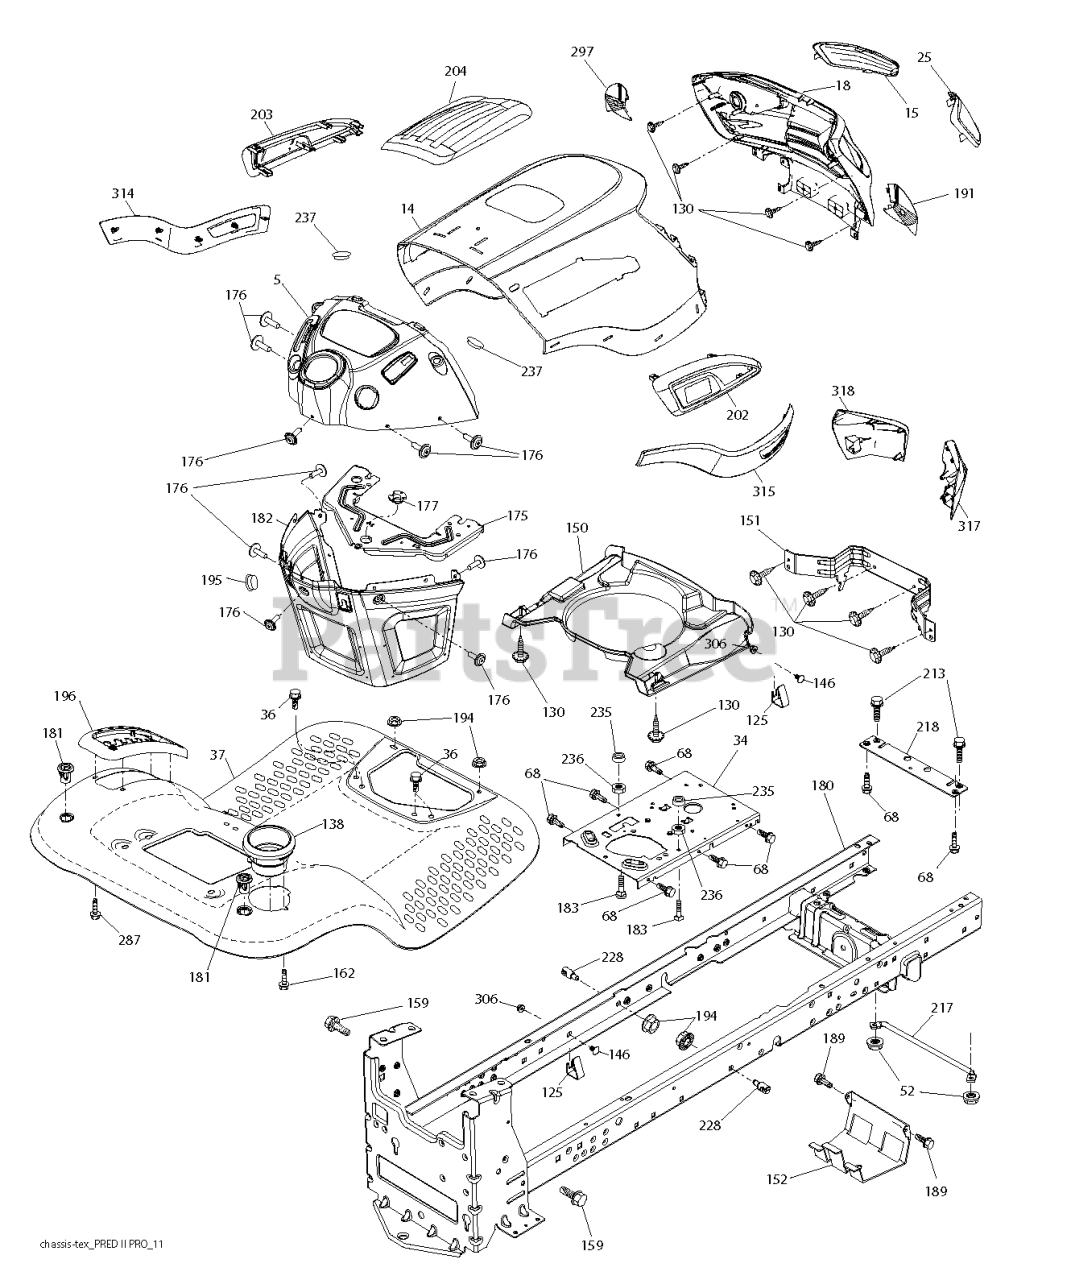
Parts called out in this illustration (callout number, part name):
5	DASHBOARD DASH.YT.PRED.REC.GA.
14	HOOD HOOD.GRILL.PREDII.YT/GT.Y
15	LENS.LH.PRED II.YT.CLR.SVC
18	GRILLE.PRED2.GT.PRO.REDMAX
25	LENS.RH.PRED II.YT.CLR.SVC
34	PLATE.ENGINE.WELDED.CHASSIS
36	SCREW 5/16"
37	FENDER.TLT.PDLCONTROL.WCUPX672
52	LOCKNUT
68	SCREW LT
125	CLIP.FUEL.LINE
130	SCREW.#10 X 0.750.BOS
138	CUPHOLDER.TL.TEX.BLACK
146	BOLT.RDHD.SHT.SQNK.3/8-16X5/8
150	PREDATOR.YT.GT.HOOD.AIR DUCT
151	BRACKET.PIVOT.PREDATOR
152	SHIELD.BROWNING.W/TEX
159	SCREW, 3/8-16X3/4
162	SCREW.HI-LO.CONSOLE
175	PLATE.CROSSMEMBER.HUSQ
176	SCREW.#10-24X5/8.RN.QU
177	BUSHING STEERING
180	CHASSIS
181	BUSHING.MNT.FEND.CRGO.
182	DASH.LOWER.COMMON.12V.ADAPTOR
183	BOLT.5/16-18X1-1/4 FULL THD
189	SCREW
191	INSERT INSERT.REFLECTIVE.RH
194	NUT LOCK HEX FLANGE 5/16-18
195	PLUG.HOLE.DASH.LOWER.12V.BLK
196	CONSOLE.ASM.DECKLFT.BL/RBT.TLT
202	VENT SIDE. HOOD. PREDATOR II.
203	VENT SIDE. HOOD. PREDATOR II.
204	VENT ASM.TOP.PRED GT PRO.428
213	BOLT
217	ROD.PIVOT.HOOD
218	X-PIECE.HOOD.STOP.NON/
228	STUD.FASTNER.W/ANTI-ROTATE
235	SPACER FENDER
236	NUT.CENTERLOCK.5/16-
237	PLUG.MOUNT.CARGO.BLK
287	SCREW 1/4X20
297	INSERT INSERT.REFLECTIVE.LH
306	NUT LOCK FLG 3/8-16 UNC
314	TRIM SUBASM. PREDATOR II. YT/G
315	TRIM SUBASM. PREDATOR II. YT/G
317	BUMPER CORNER. PREDATOR II. GT
318	BUMPER CORNER. PREDATOR II. GT
